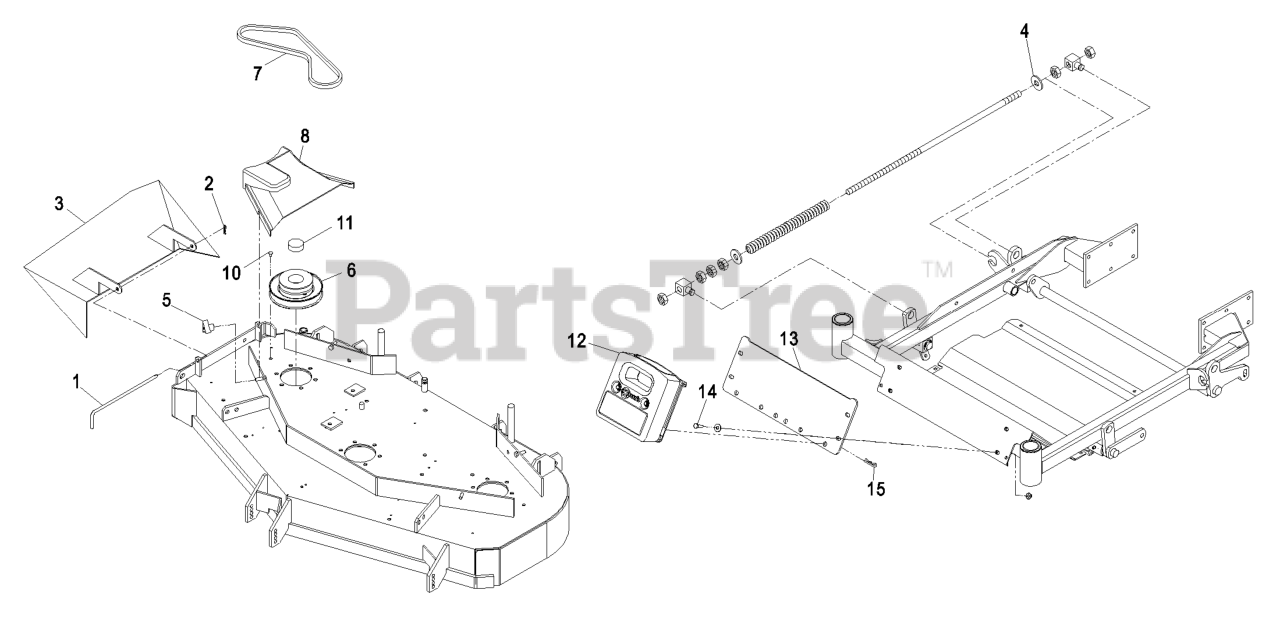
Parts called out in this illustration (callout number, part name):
1	PIN, CHUTE PIVOT PLTD
2	PIN-COTTER
5	KNOB-3 PRONG
6	SHEAVE, BLOWER DR 48"
7	BELT-BLOWER
8	COVER, BELT 44/48
9	Spacer, Counterweight
10	SCREW-HH
11	PLUG, BLACK NYLON 1.75
12	ASM,CAST WEIGHT
13	PLATE,WEIGHT ASM MOUNT
14	SCREW-HH
15	Hairpin, Cotter
